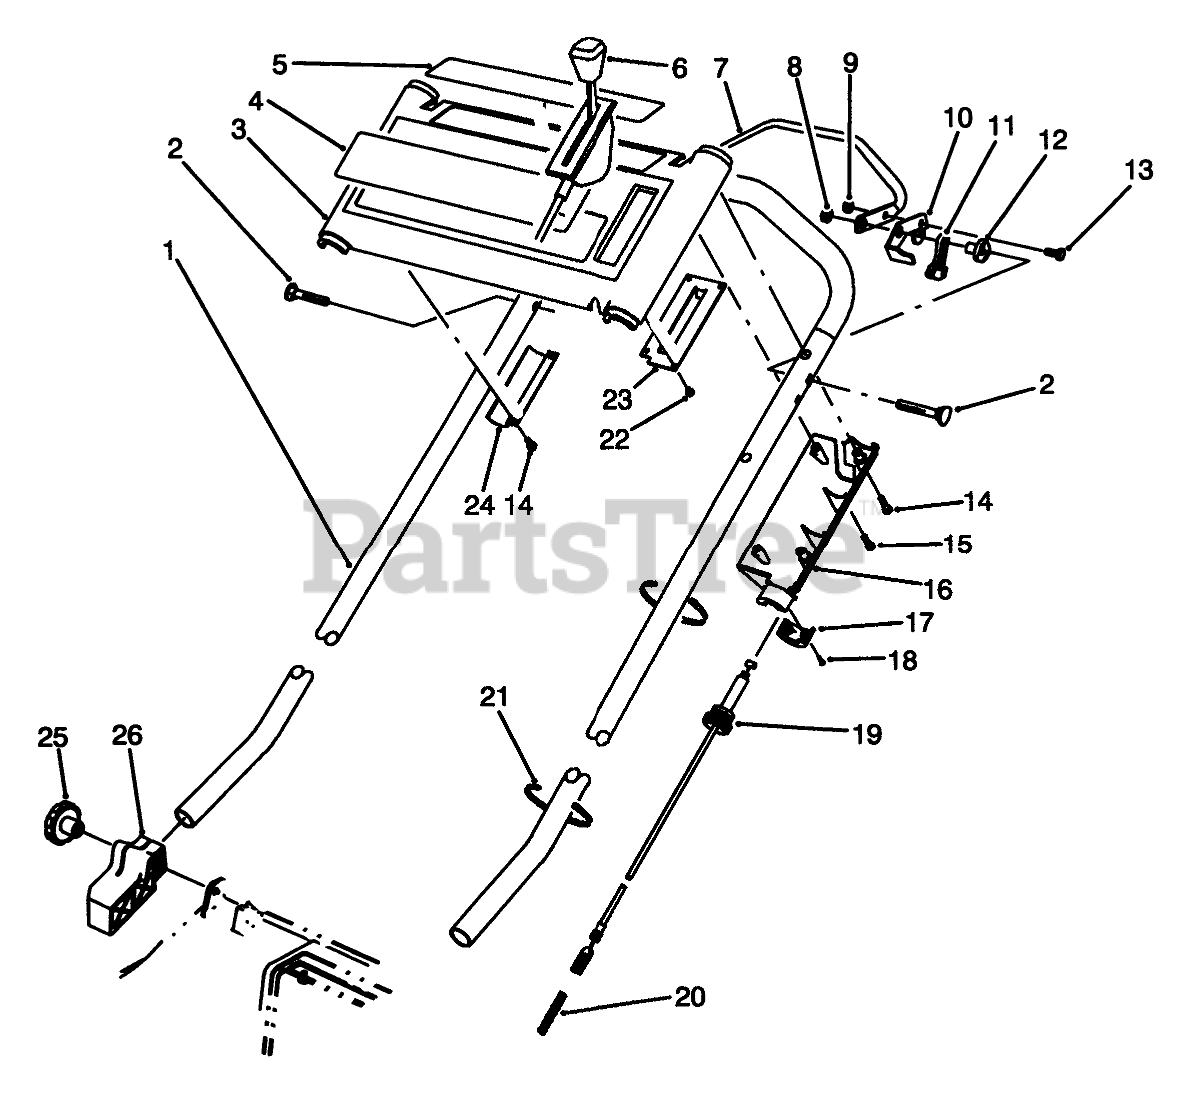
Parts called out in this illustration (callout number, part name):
1	Handle
2	SCREW-HANDLE
3	Panel-Control (Incl. Ref. #4 & 5)
4	DECAL - PANEL 4-CYCLE
5	DECAL - PANEL (DANGER)
6	Control-Throttle Bend Type #1 Sheath Lg. 55.50 Wire Lg. 2 1/2
7	CONTROL BAR
8	NUT-LOCK, NI
9	NUT-LOCK, NI
10	CONTROL LEVER
11	LEVER-TRACTION
12	SPACER-SUPPORT
13	SCREW-HH
14	SCREW-PPH, PLASTITE
15	Screw
16	Cover-Throttle Lower
17	LOWER THROTTLE CAP
18	#4-14X.62 PLASTITE SCW
19	TRACTION CABLE
20	SPRING-COMPRESSION
21	TIE-CABLE
22	#6-19X.25 PLASK FORM SC
23	THROTTLE PLATE
24	Bracket-Panel
26	MOUNT-HANDLE, RH
